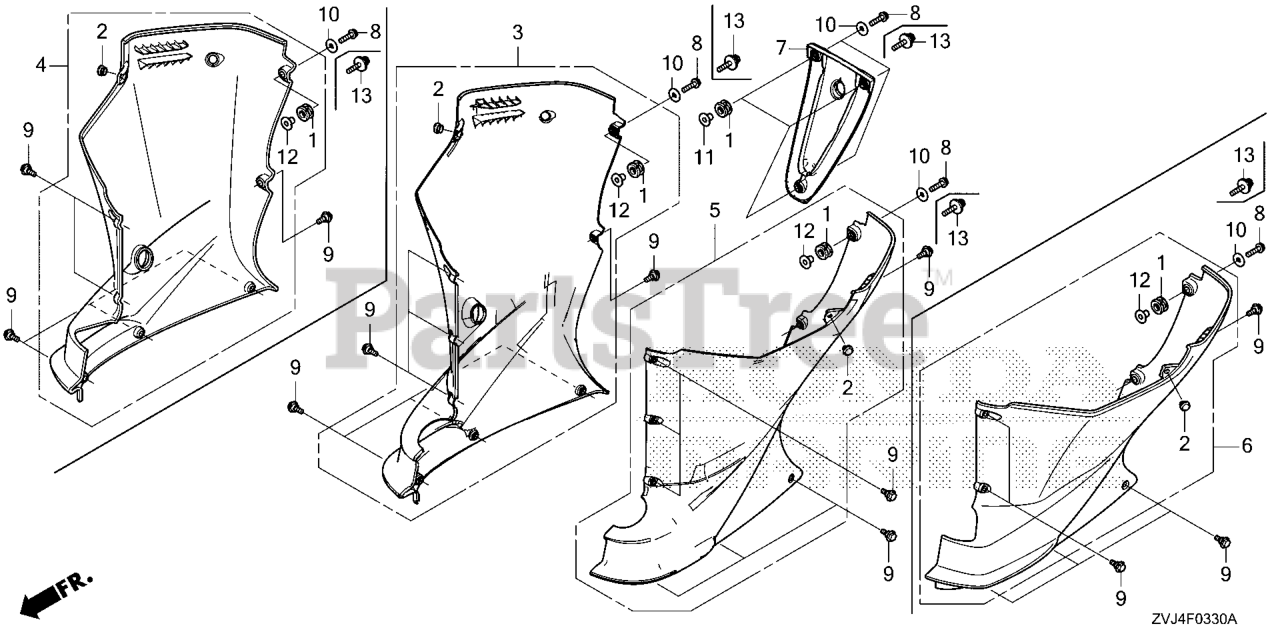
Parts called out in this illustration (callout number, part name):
1	GROMMET, CASE (LOWER)
2	RUBBER, STOPPER
3	COVER, R. ENGINE (LOWER) *NH565* (XL) (GRAND PRIX WHITE)
3	COVER, R. ENGINE (LOWER) *NHB14M* (XL) (AQUA MARINE SILVER METALLIC)
5	COVER, L. ENGINE (LOWER) *NH565* (XL) (GRAND PRIX WHITE)
5	COVER, L. ENGINE (LOWER) *NHB14M* (XL) (AQUA MARINE SILVER METALLIC)
7	COVER, RR.
8	BOLT, FLANGE (6X25)
9	BOLT, SPECIAL (6X17)
10	WASHER, PLAIN (6MM)
11	COLLAR (12X6.5)
12	COLLAR (12X6.5)
13	BOLT, WASHER (6X25)
